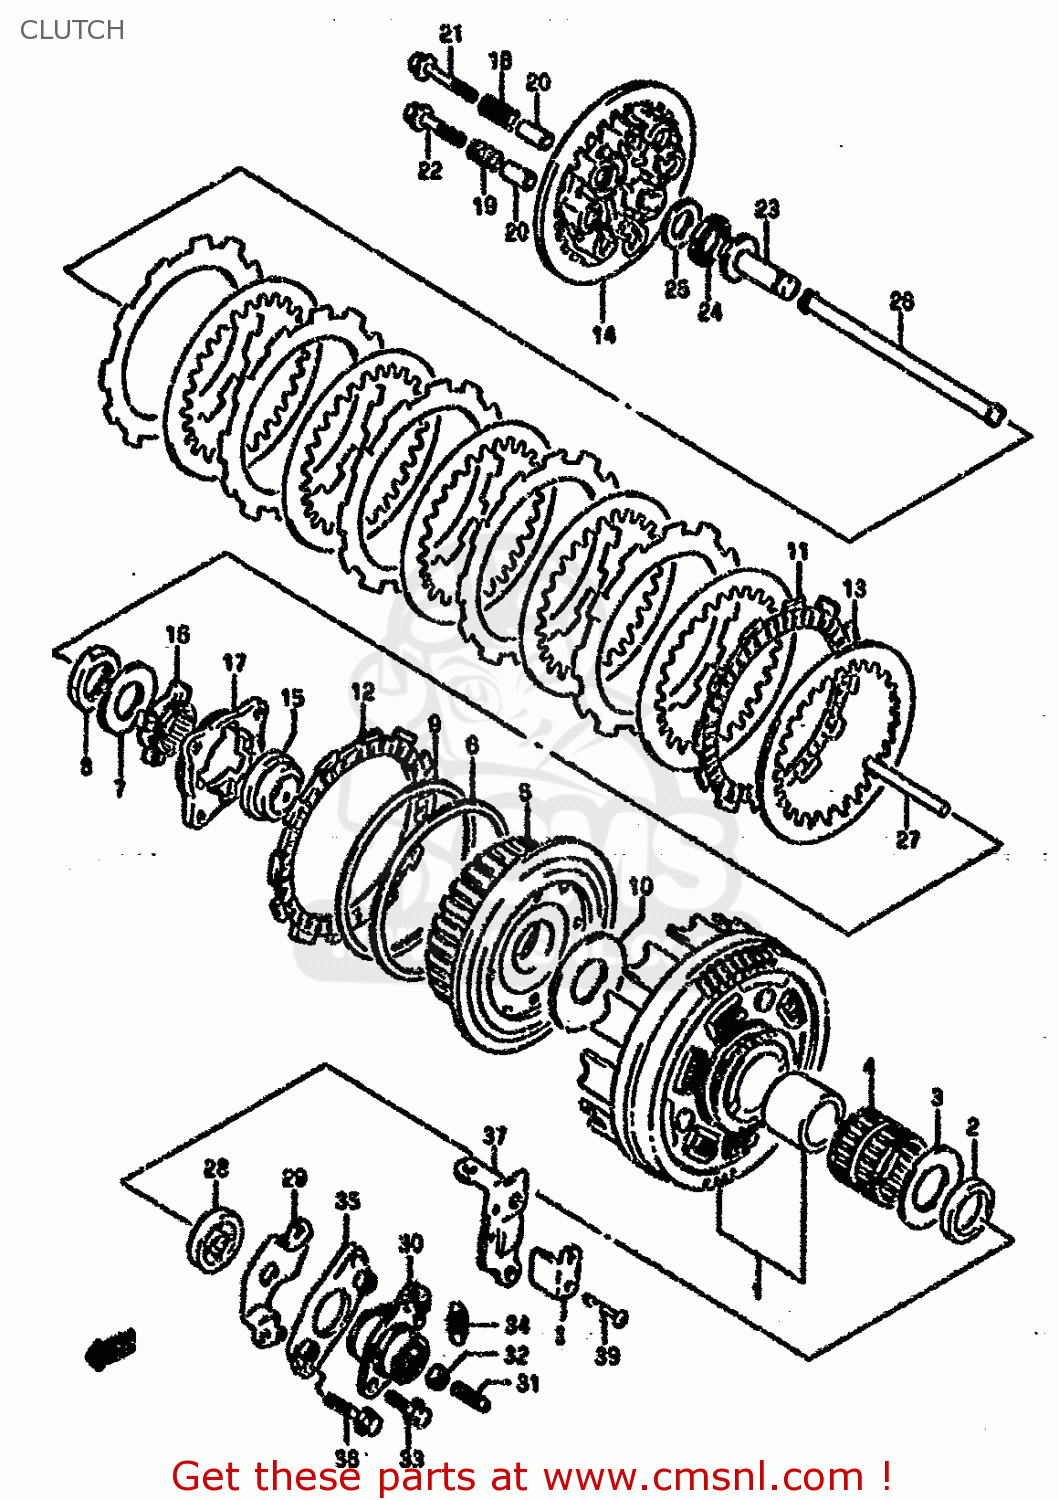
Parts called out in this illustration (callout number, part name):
1	GEAR ASSY,PRIMARY(NT:71)
2	SPACER(25X38X6.5)
3	WASHER(25X50X2.5)
4	BEARING(35X40X35.8)
5	HUB,CLUTCH SLEEVE
6	SEAT,WAVE WASHER(T:1.4)
7	WASHER
8	NUT
9	WASHER
10	WASHER(25X60X2.5)
11	PLATE,CLUTCH DRIVE (NAS)
12	PLATE,CLUTCH DRIVE(T:3.5) (NAS)
13	PLATE,CLUTCH DRIVEN(T:1.6) (NAS)
14	DISC,CLUTCH PRESSURE
15	SPACER,CLUTCH SLEEVE HUB
16	CAM,CLUTCH NO.1
17	CAM,CLUTCH NO.2
18	SPRING
19	SPRING
20	SPACER (6,1X9X24.1)
21	BOLT(6X40)
22	BOLT(6X32.5)
23	PIECE,CLUTCH PUSH
24	BEARING(15X28X2)
25	WASHER(15.5X28X1)
26	ROD,CLUTCH
27	ROD,CLUTCH PUSH,L
28	SEAL,OIL(6X34X11)
29	RETAINER,CL PUSH ROD OIL SEAL
30	SCREW ASSY,CLUTCH RELEASE
31	SCREW(6X25)
32	NUT
33	BOLT
34	SPRING
35	PLATE,CLUTCH RELEASE SCREW
36	BOLT
37	GUIDE,CLUTCH CABLE
38	PLATE,CLUTCH CABLE GUIDE
39	SCREW (5X8)
